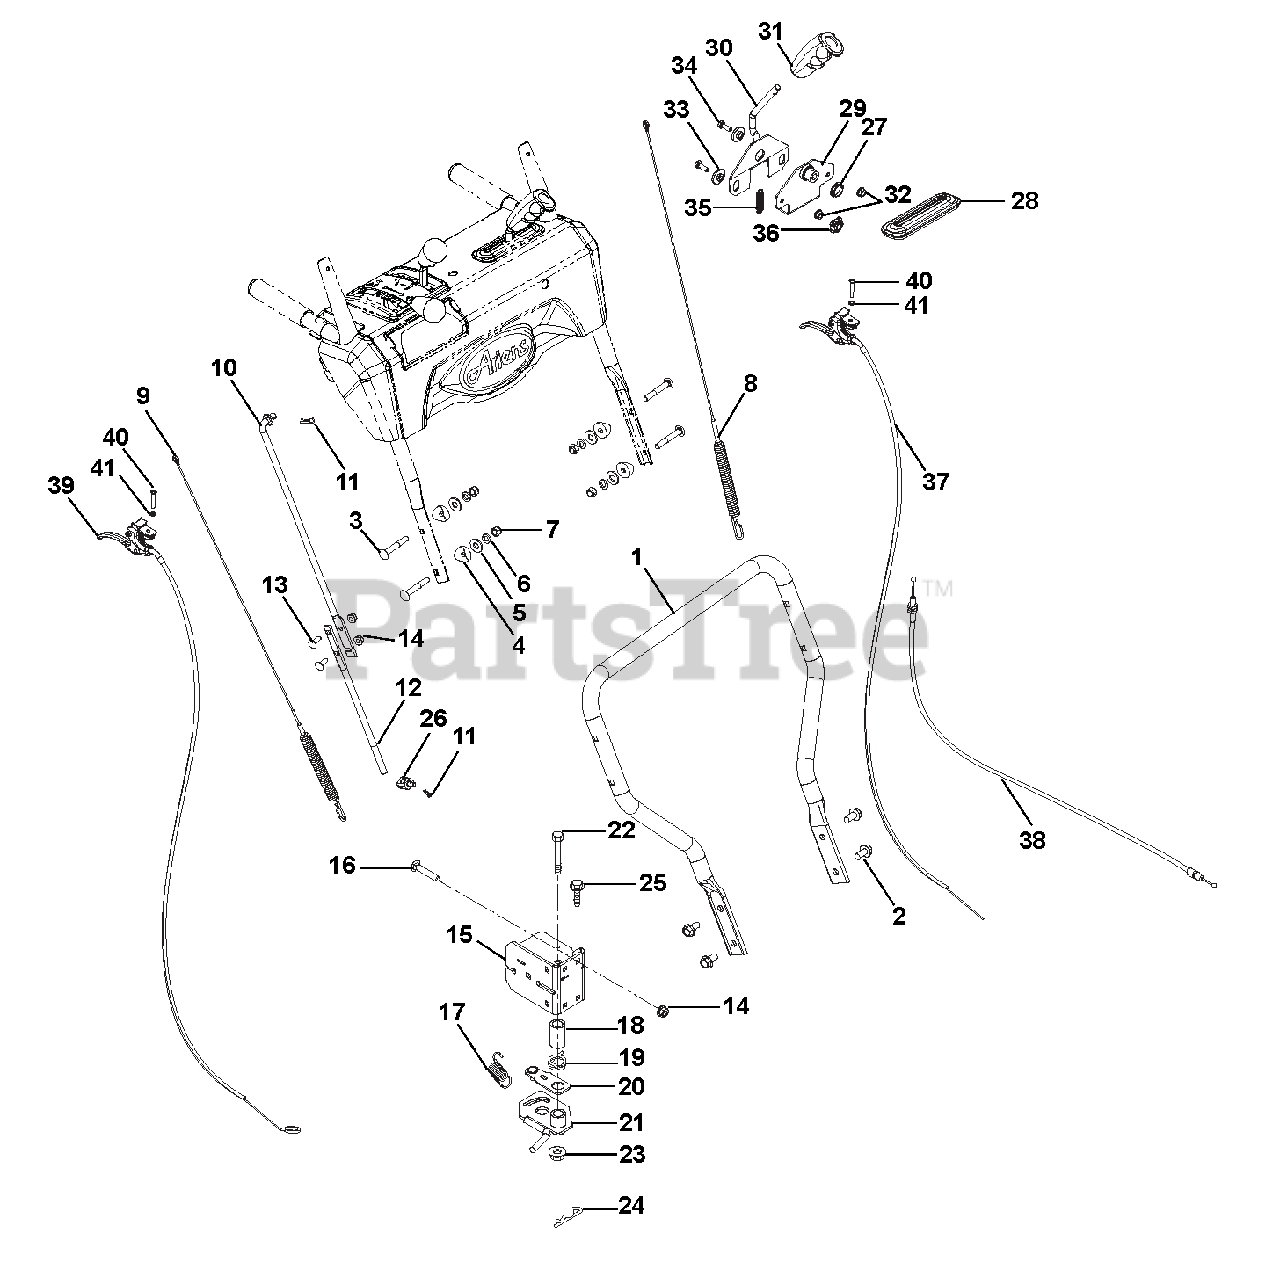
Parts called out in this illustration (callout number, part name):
1	HANDLEBAR, LOWER - DELUXE
2	BLT-SERHFWH .38-16X.75 YWZC
3	@BLT-RDHDSQNK .31-18X2.25 G5YZ
4	SPACER, HANDLEBAR
5	@WSHR-FL-STL.38X.875X.083 YWZC
6	WSHR-LK .312X.097 HVY YWZC
7	@NUT-LK-NYL .312-18 YWZC
8	CABLE, UPPER TRACTION
9	CABLE, AUGER (DELUXE & PRO)
10	ROD, SHIFT - UPPER
11	PIN-HAIR INT .08X.18X1.18 YWZC
12	ROD, SHIFT - LOWER
13	@BLT-RDHDSQNK .25-20X.75 G5YZ
14	@NUT-LK-TOP-FLG .25-20 YWZC
15	BRACKET, HEIGHT ADJUSTER
16	@BLT-RDHDSQNK .25-20X.75 G5YZ
17	SPRING-EXT .047 X .438 X 1.85
18	BSHG-SLV .385X.500X1.045
19	SG-TORS .067X.88
20	ARM, OVERTRAVEL
21	LOCK, HEIGHT ADJUSTER
22	@BLT-HEX .38-16X1.75 GR5 YWZC
23	NUT-LK-CTR-FLG .38-16 YWZC
24	PIN-HAIR INT .06X.18X.77
25	SCR-TAP .25-20X.50 HWH TR YWZ
26	PIVOT,SHIFT ROD .375-16(TRUNN)
27	BUSHING, POLYLINER-.75 SNAPIN
28	GROMMET-BOOT, QUICKTURN
29	MOUNT, CHUTE CONTROL
30	LEVER, CHUTE CONTROL
31	CONTROL HANDLE, QUICK TURN
32	@NUT-LK-TOP-FLG .25-20 YWZC
33	BSHG-FLG .265X.448X.243X1.00
34	@BLT-HEX .25-20X.75 GR5 YWZC
35	SG-TENS .048X.44X1.75 WLD 9
36	CRANK BUSHING, NYLON CHUTE BK
37	CABLE, TRIGGER, REMOTE WHEEL
38	CABLE, CHUTE LOCK
39	CABLE, TRACK REMOTE
40	SCR-MCH .25-20X1.50 OVAL HD
41	WSHR-LK-INT .250 TH TYA
